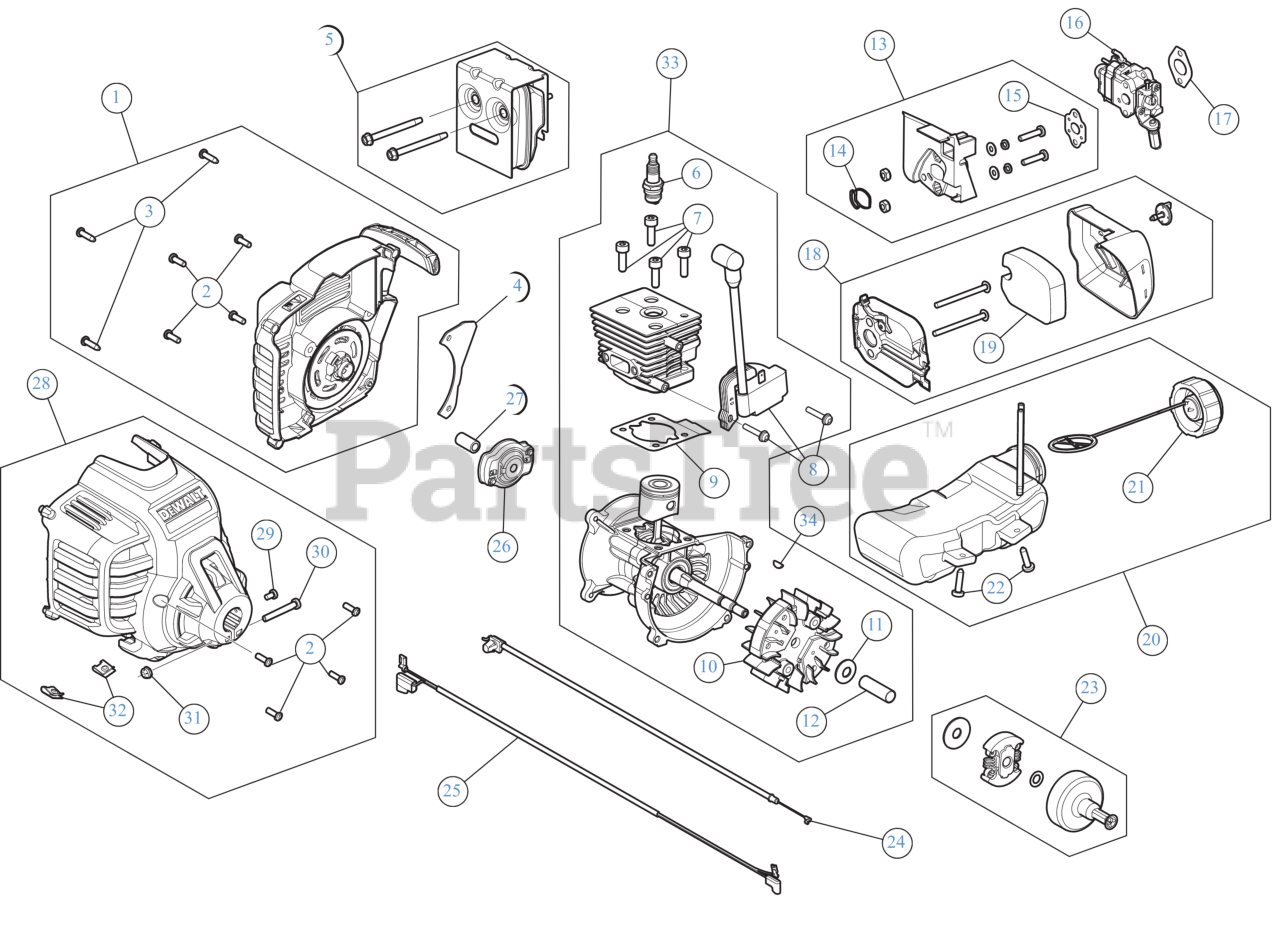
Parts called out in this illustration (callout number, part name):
1	STARTER HOUSING 27CC
2	SCREW #
3	SCREW 8-16 x 3/4
4	STARTER GUARD
5	MUFFLER ASSEMBLY
6	SPARK PLUG
7	SCREW 1/4 x 20 x .8125
8	MODULE 27CC
9	GASKET CYL
10	FLYWHEEL ASSEMBLY 27CC
11	BELL WASHER
12	SPACER
13	INTAKE ASSEMBLY
14	O-RING
15	CARBURETOR GASKET
16	CARBURETOR 27cc
17	GASKET CARB
18	AIR CLEANER
19	AIR FILTER
20	FUEL TANK
21	FUEL CAP
22	SCREW:10-6 x .75
23	SMALL CLUTCH ASSEMBLY W/SMALL DRUM
24	THROTTLE CABLE
25	LEAD WIRES
26	PAWL ASSEMBLY AC5
27	ELECTRIC START ADP
28	CLUTCH COVER
29	SCREW, 8-32 x .312 P
30	SCREW
31	HEX NUT
32	NUT, TINNERMAN U-T
33	SHORT BLOCK 27CC
34	WOODRUFF KEY #403-.125 x .375
